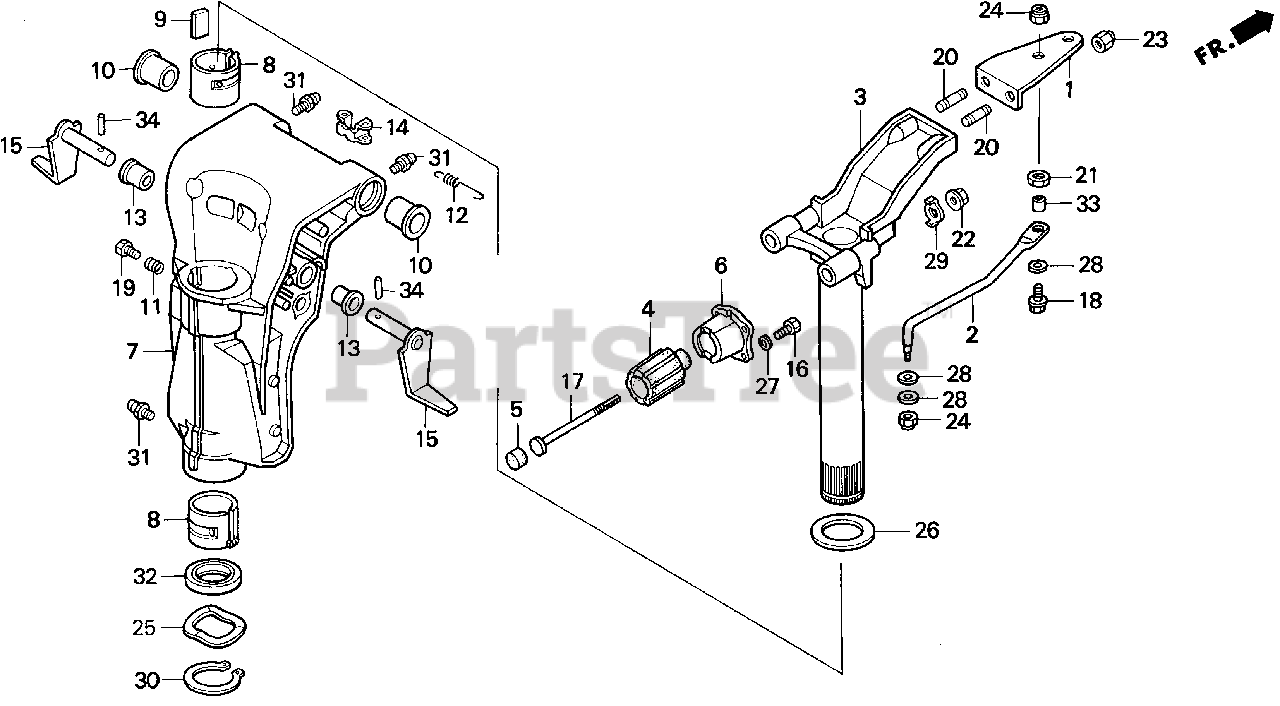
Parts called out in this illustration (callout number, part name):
1	PLATE, STEERING
2	ROD, STEERING
3	FRAME, MOUNTING *NH282MU* (OYSTER SILVER METALLIC-U)
4	RUBBER, MOUNTING (UPPER)
5	RUBBER, MOUNTING (UPPER) (B)
6	HOLDER, MOUNTING (UPPER) *NH8* (DARK GRAY)
7	CASE, SWIVEL *NH282MU* (OYSTER SILVER METALLIC-U)
8	LINER, SWIVEL CASE
9	BLOCK, FRICTION
10	BUSH, SWIVEL CASE
11	SPRING, FRICTION ADJUSTING
12	SPRING, TILT LEVER
13	BUSH, TILT ARM
14	BRACKET, TILTING
15	PLATE, TILT ARM
16	BOLT, HEX. (6X18)
17	BOLT, SPECIAL (10X130)
18	BOLT (3/8-24 UNF)
19	BOLT, SPECIAL (8X20)
20	BOLT, STUD (10X28)
21	NUT (3/8-24 UNF)
22	NUT, FLANGE (10MM)
23	NUT, SELF-LOCK (10MM)
24	NUT, SELF-LOCK (3/8-24UNF)
25	WASHER, WAVE (40MM)
26	WASHER, THRUST (34MM)
27	WASHER, PLAIN (6MM)
28	WASHER (10MM)
29	WASHER, SPECIAL
30	CIRCLIP (OUTER) (39MM)
31	NIPPLE, GREASE
32	OIL SEAL (39.5X52X6)
33	COLLAR, STEERING ROD
34	PIN, SPRING (2.5X20)
